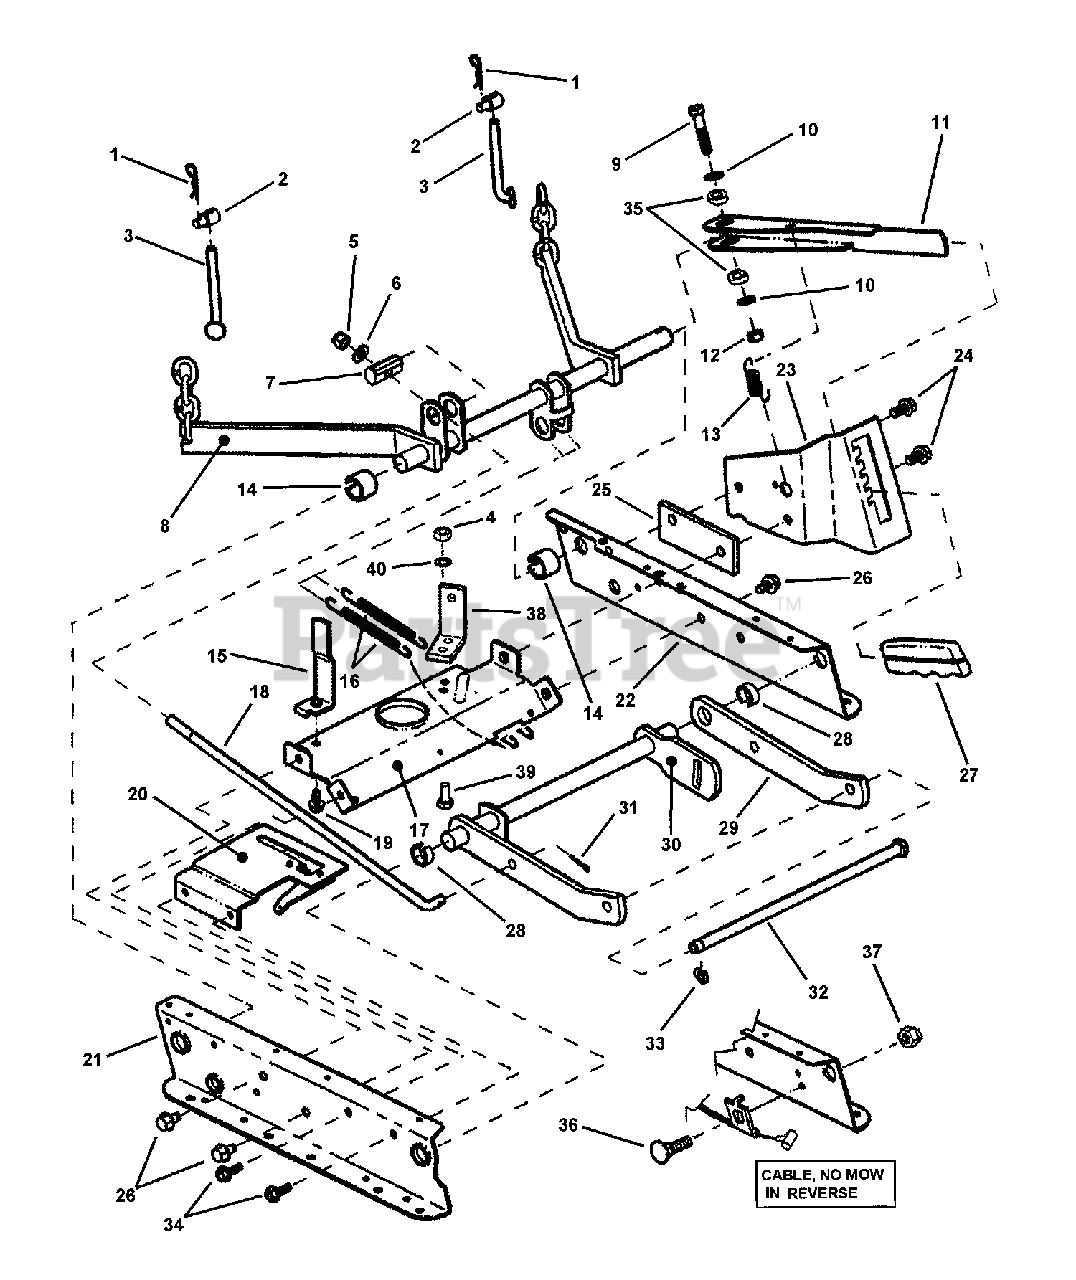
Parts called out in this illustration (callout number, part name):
1	HAIR PIN, 3/32 x 1-1/2"
2	SWIVEL, Adjustable
3	ADJUSTER, Chain (5/16-18 thread)
4	NUT, 5/16-24 Hex, GR 5
5	NUT, 3/8-24 Hex Nyloc
6	WASHER, 3/8" Flat
7	PIVOT, Leveling
8	WELDMENT, Rear Lift Arm
9	SCREW, 3/8-24 x 1-3/4" Hex Head Cap, GR 5
10	WASHER, 13/32 x 1-1/4" Flat
11	LEVER, Height of Cut
12	NUT, 3/8-24 Hex Center Lock
13	SPRING, Lever
14	RING, Rear Lift Arm (Blue)
15	GUIDE, Belt
16	SPRING, Assist
17	BRACE, Top
18	ROD, Leveling (3/4-24 thread)
19	SCREW, 5/16-18 x 5/8" Hex Washer Self-Tap
20	ASSEMBLY, Clutch Plate
21	RAIL, Deck Lift, Right Hand
22	RAIL, Deck Lift, Left Hand
23	DETENT, Height Adjust
24	SCREW, 3/8-16 x 1" Hex Washer Self-Tap
25	SPACER, Detent
26	SCREW, 3/8-16 x 5/8" Hex Washer Self-Tap
27	GRIP, Height Adjustment Lever
28	RING, Front Lift Arm (Red)
29	ARM, Front Lift
30	WELDMENT, Front Lift Arm
31	PIN, 1/8 x 3/4" Cotter
32	ROD, Deck Support (Front Lift Arm to Front End)
33	RING, .438 External Retaining
34	SCREW, 5/16-18 x 1/2" Hex Washer Self-Tap
35	SPACER, Deck Lift
36	BOLT, #10-24 x 1" Flat Head Square Neck
37	NUT, #10-24 Hex Nyloc
38	ANCHOR
39	SCREW, 5/16-24 x 3/4" Hex Head Cap, GR 5
40	WASHER, 5/16" Internal Tooth Lock
